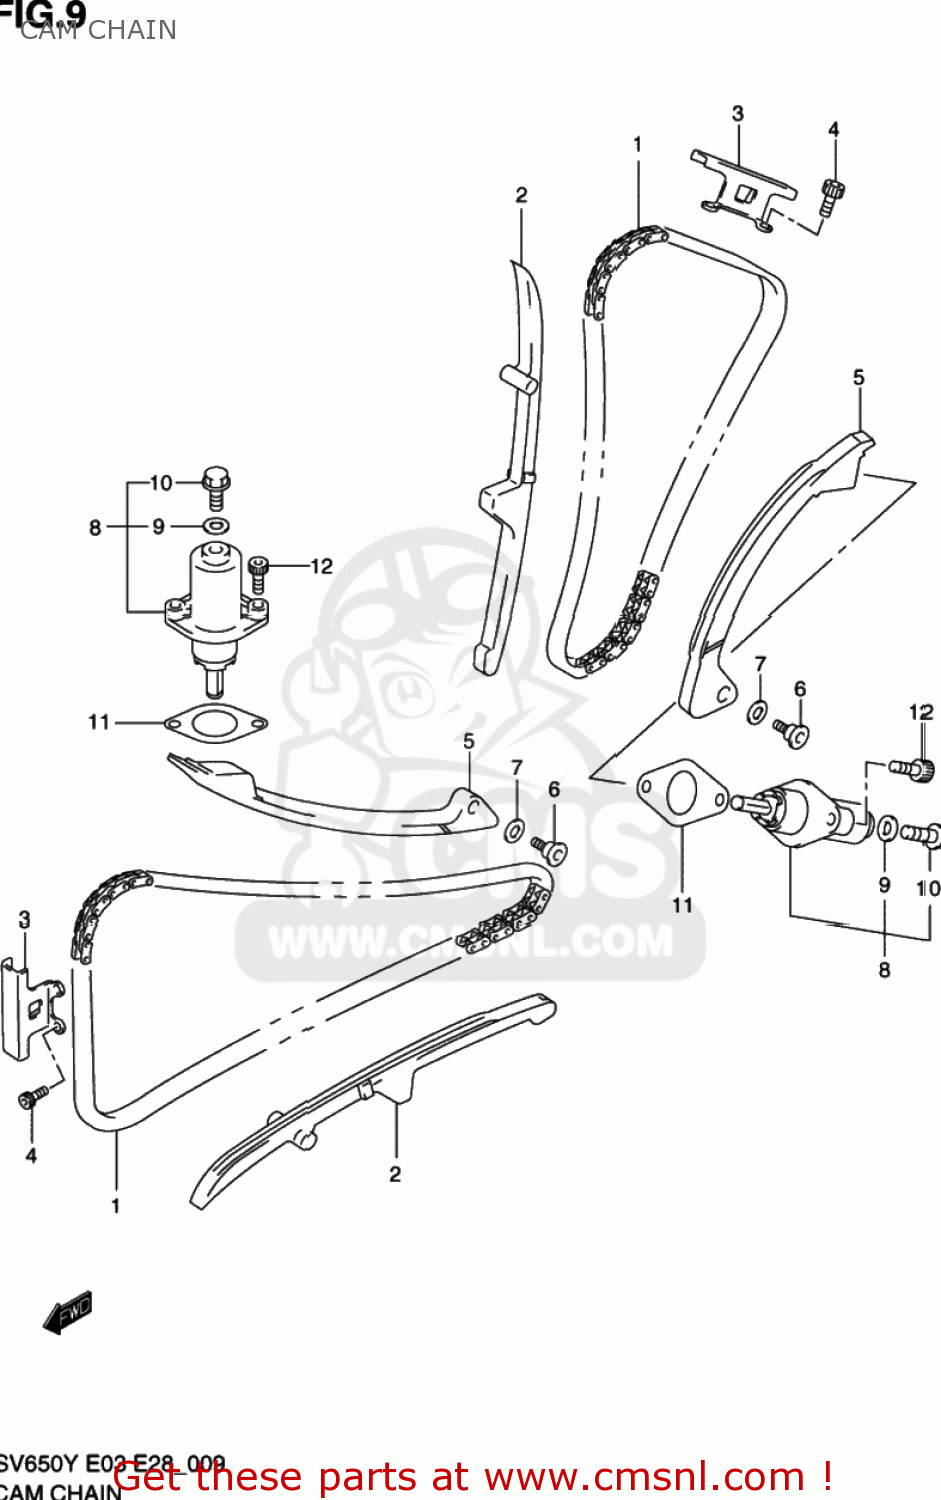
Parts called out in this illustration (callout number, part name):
1	CHAIN COMP,CAMSHAFT DRIVE
2	GUIDE,CAM CHAIN NO.1
3	GUIDE,CAM CHAIN NO.2
4	BOLT,STRANGER
5	TENSIONER,CAM CHAIN
6	BOLT,CAM CHAIN TENSIONER
7	WASHER
8	ADJUSTER ASSY,TENSIONER
9	GASKET,TENSIONER ADJUSTER
10	PLUG,TENSIONER ADJUSTER
11	GASKET,TENSIONER ADJUSTER (NAS)
12	BOLT,CL.COVER
